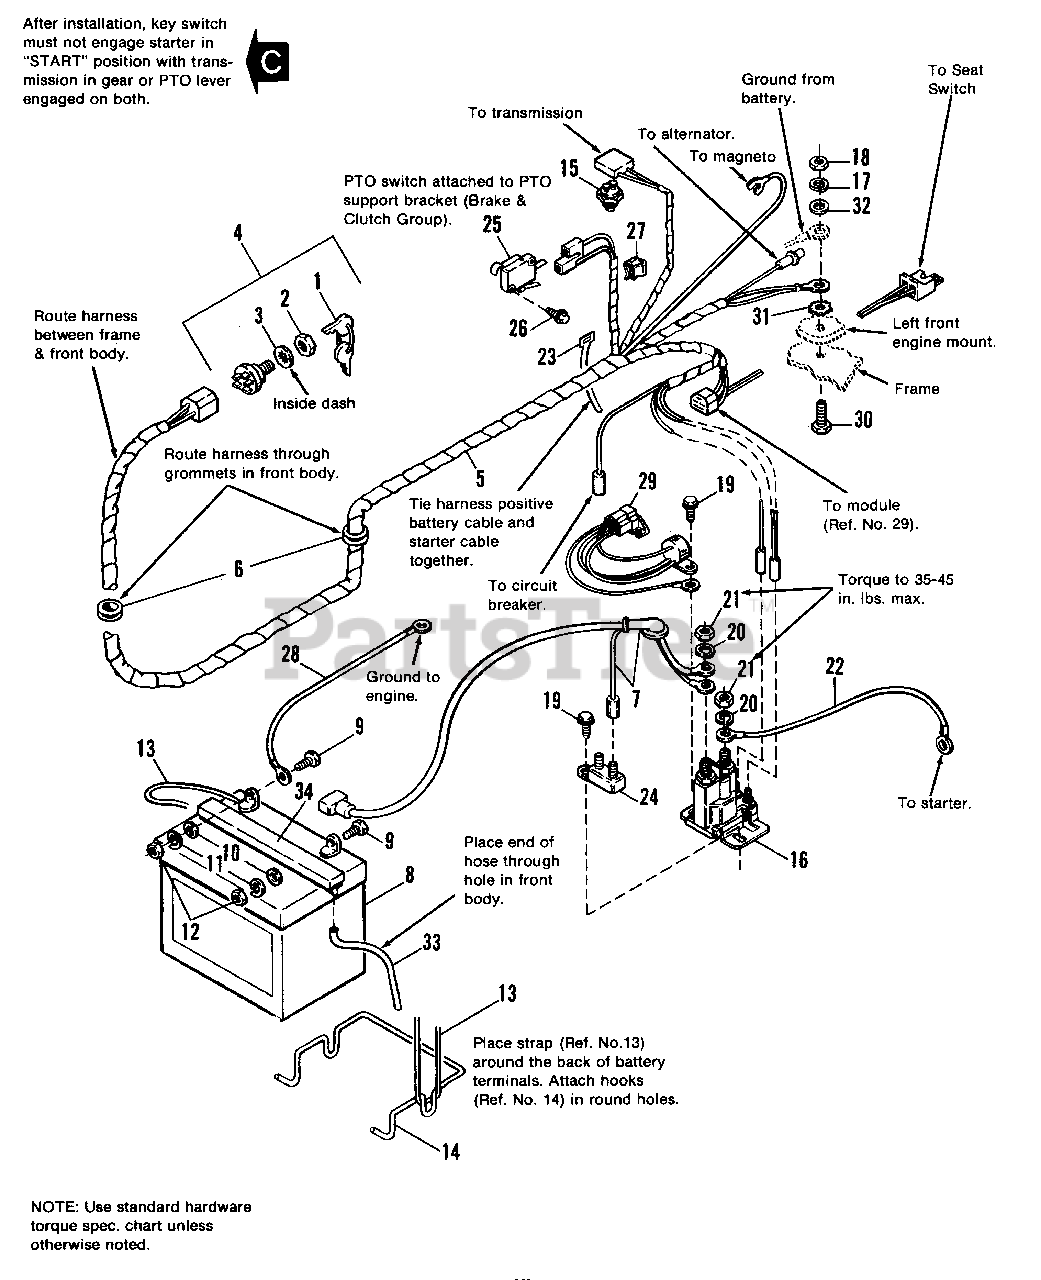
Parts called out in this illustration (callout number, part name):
2	NUT
3	LOCKWASHER, Internal Tooth, 5/8
4	SWITCH, Key (Incl. Ref. Nos. 1, 2 & 3)
5	HARNESS ASSY.
7	CABLE ASSY. (Batt to Solenoid)
8	BATTERY, 12 Volt
9	CAPSCREW, Hex, 1/4-20 x 3/4
10	WASHER, Plain, 1/4
11	LOCKWASHER, 1/4
12	NUT, Hex, 1/4-20
13	STRAP, Battery
14	BRACE, Battery
15	SWITCH, Transmission Interlock
16	SOLENOID
17	LOCKWASHER, 3/8
18	NUT, 3/8-16
19	SCREW, Hex, Taptite, 1/4-20 x 5/8 (Zinc Pltd.)
20	LOCKWASHER 5/16
21	LOCKNUT, Hex, 5/16-18
22	CABLE ASSY. (Solenoid to Starter)
24	BREAKER, Circuit
25	SWITCH, P.T.O. Interlock
26	SCREW, Hex, Taptite, #50-40 x 3/4
28	CABLE (Battery to Ground)
29	MODULE, Interlock
30	CAPSCREW, Taptite 3/8-16 x 2
31	LOCKWASHER, Ext Tooth, 3/8 (Zinc Pltd.)
32	WASHER, 3/8
33	HOSE, 3/8 I.D., 1/2 O.D. x 23-1/2" Long
34	VENT, Battery
